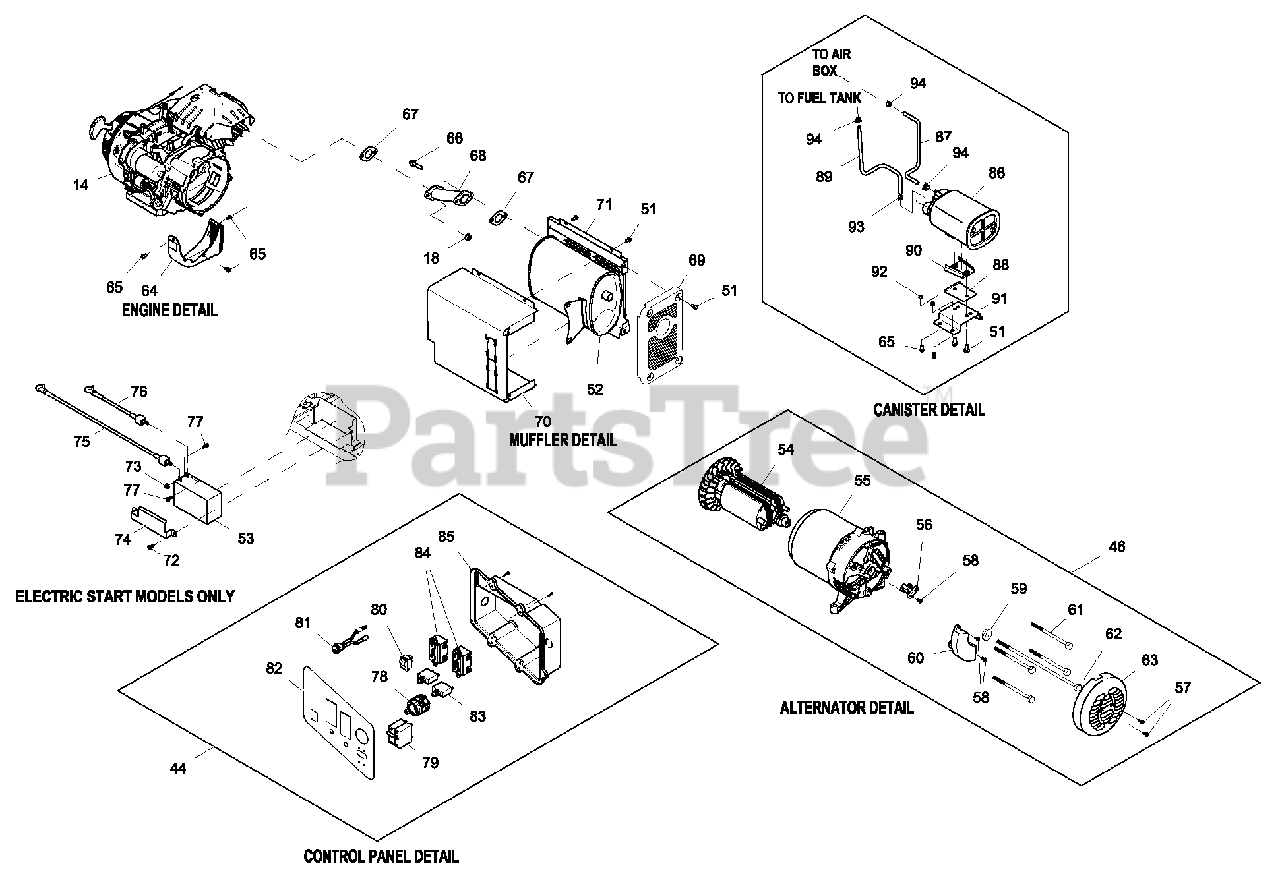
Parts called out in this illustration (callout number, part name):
52	MUFFLER 5.5-7.5KW HNYWL CARB
53	BATTERY 12V10AH SEALED
56	ASSEMBLY,BRUSH
57	SCREW HHFC M5-0.8X12
58	SCREW HHFC M5-0.8X16
59	WASHER FLAT M10
60	AVR 5.5-7.5KW ALT
63	COVER ALTERNATOR INLET 5-7KW
64	SCROLL, HONEYWELL
65	SCREW HHC M5-0.8X 10 C8.8
66	SCREW HHFC M8-1.25 X 35 G8.8
67	GASKET, EXHAUST, 389CC
69	MUFFLER SHIELD FRONT HONEYWELL
70	MUFFLER SHIELD ALT SIDE HNYWL
71	MUFFLER SHIELD FRAME SIDE HW
73	NUT FLANGE M5-0.8 NYLOCK
74	BRACKET BATTERY GP 5.5-7.5E
75	WIRE ASSY,BAH NEG,GRN
76	WIRE ASSY,BAH POS.RED
77	SCREW HHC M5-0.8X 12 C8.8
78	OUTLET 30A120/250V SPCGR
83	CB 20A1P 120V CUL/CSA JOEMEX
84	OUTLET 20A120V GFCIGF20BK
85	PANEL,CONTROL BACK BOX H PORT
86	CARBON CANISTER
87	BREATHER TUBE, CARBON CANISTER
88	BRKT CARBON CANISTER STOP
89	EVAPORATIVE HOSE HNYWL CARB
90	WLDMNT BRKT CARBON CANISTER MT
91	BRKT FRAME TO CARBON CANISTER
92	NUT HEX LOCK M5-0.8 NYINS ZINC
93	CLAMP HOSE BAND .41
94	CLAMP HOSE BAND .50
